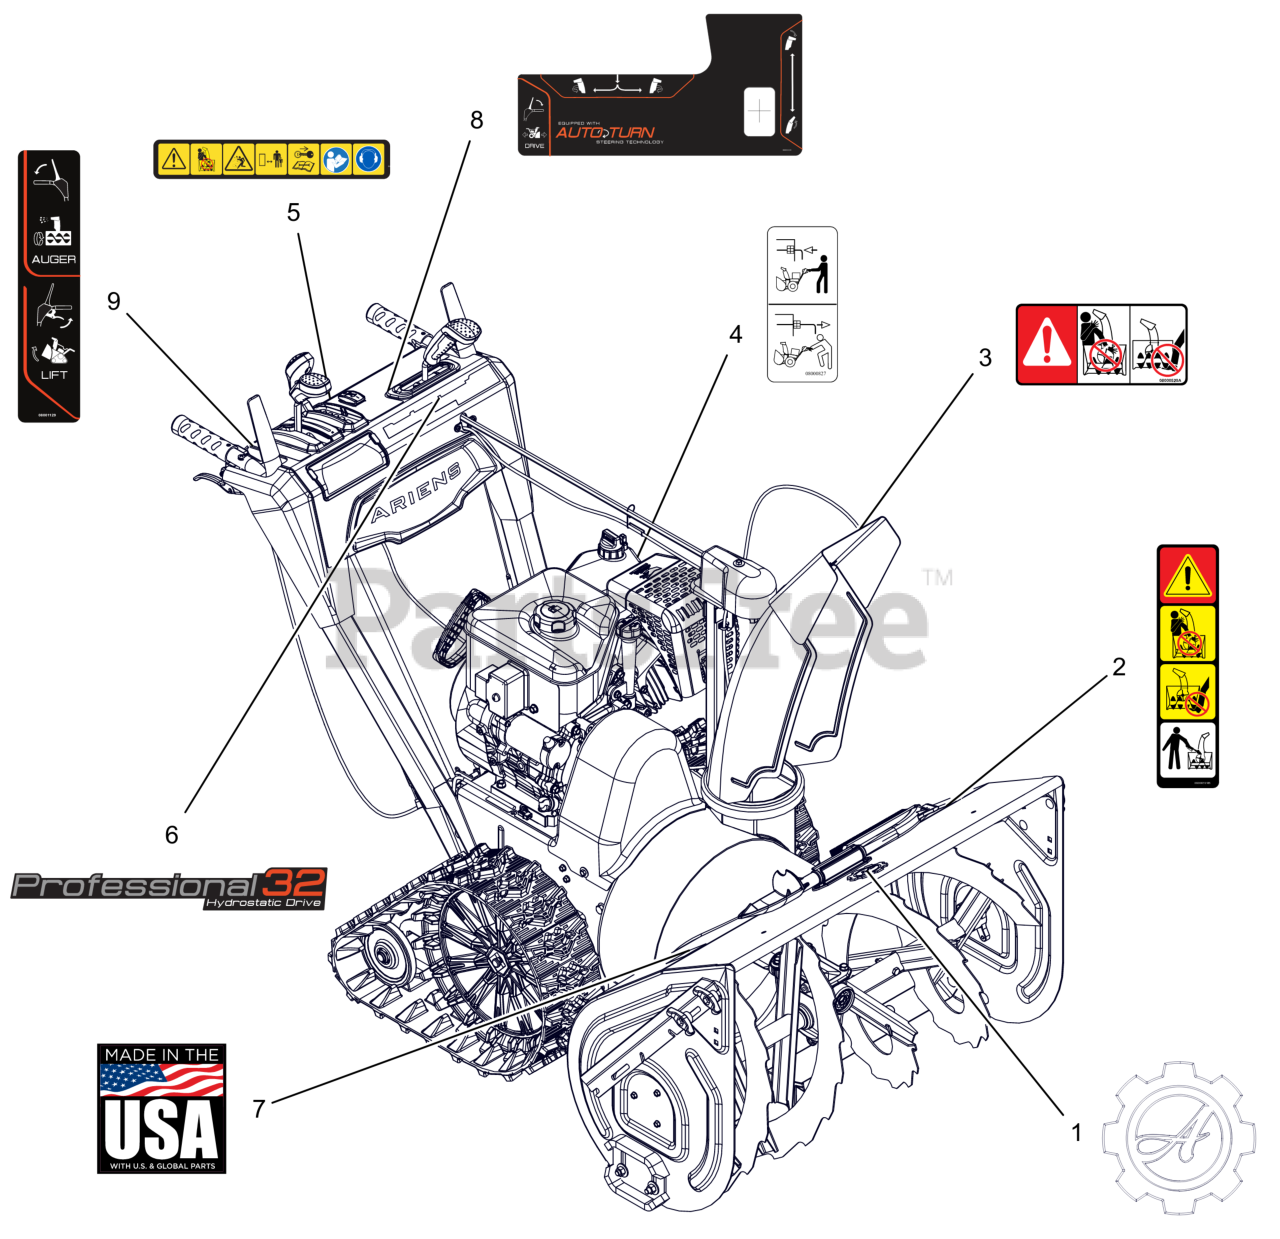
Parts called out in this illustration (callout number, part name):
1	DECAL, ARIENS-GEAR BADGE -THK
2	DECAL, DANGER - ROTATING PARTS
3	DECAL, DANGER
4	DECAL, BYPASS
5	DECAL,DASH - SAFETY
6	DECAL, DASH - PRO HYDRO 32
7	DECAL, MADE IN USA
8	DECAL,CONTROL-LG QT2
9	DECAL,CONTROL-RH TRACK
